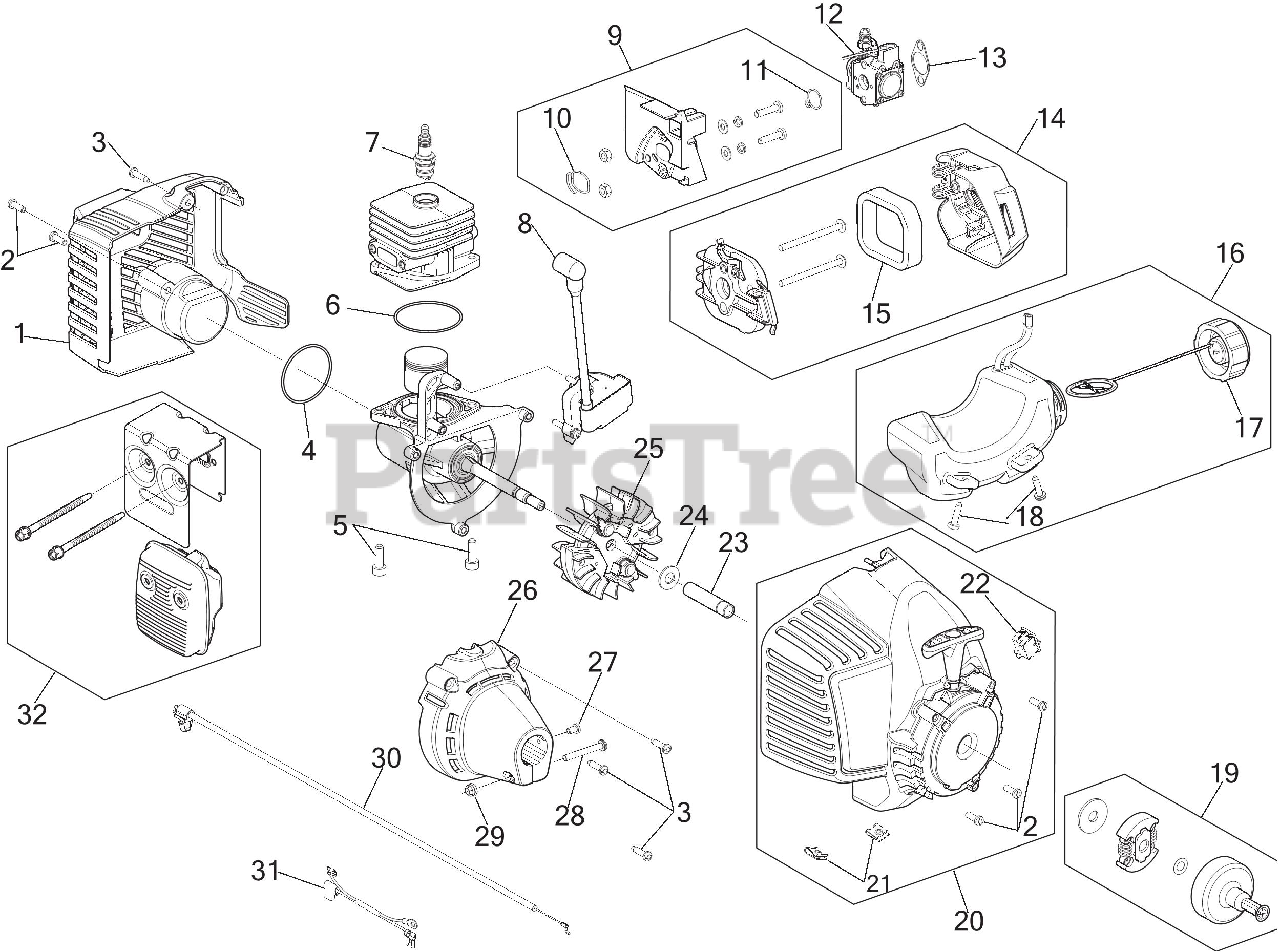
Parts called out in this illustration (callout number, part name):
1	ENGINE COVER RR
2	SCREW:10-32X.562:#8P
3	SCREW, #8-16X.750 PH
4	O-RING
5	SCREW, 1/4-20 x .75
6	O-RING
7	SPARK PLUG
8	MODULE ASSEMBLY RFI
9	INTAKE ASSEMBLY
10	O-RING
11	O-RING
12	CARBURETOR
13	GASKET CARB
14	AIR CLEANER ASSEMBLY
15	AIR FLITER
16	FUEL TANK ASSEMBLY
17	FUEL CAP ASSEMBLY
18	SCREW 10-6 x .75
19	SMALL CLUTCH ASSEMBLY W/SMALL DRUM
20	STARTER HOUSING ASSEMBLY (RED)
21	NUT, TINNERMAN U-T
22	SW, MOMENTARY ON/O
23	SPACER
24	BELL WASHER
25	FLYWHEEL ASSEMBLY
26	CLUTCH COVER
27	SCREW, 8-32 x .312 P
28	SCREW
29	HEX NUT
30	THROTTLE CABLE
31	LEAD WIRES
32	MUFFLER ASSEMBLY
